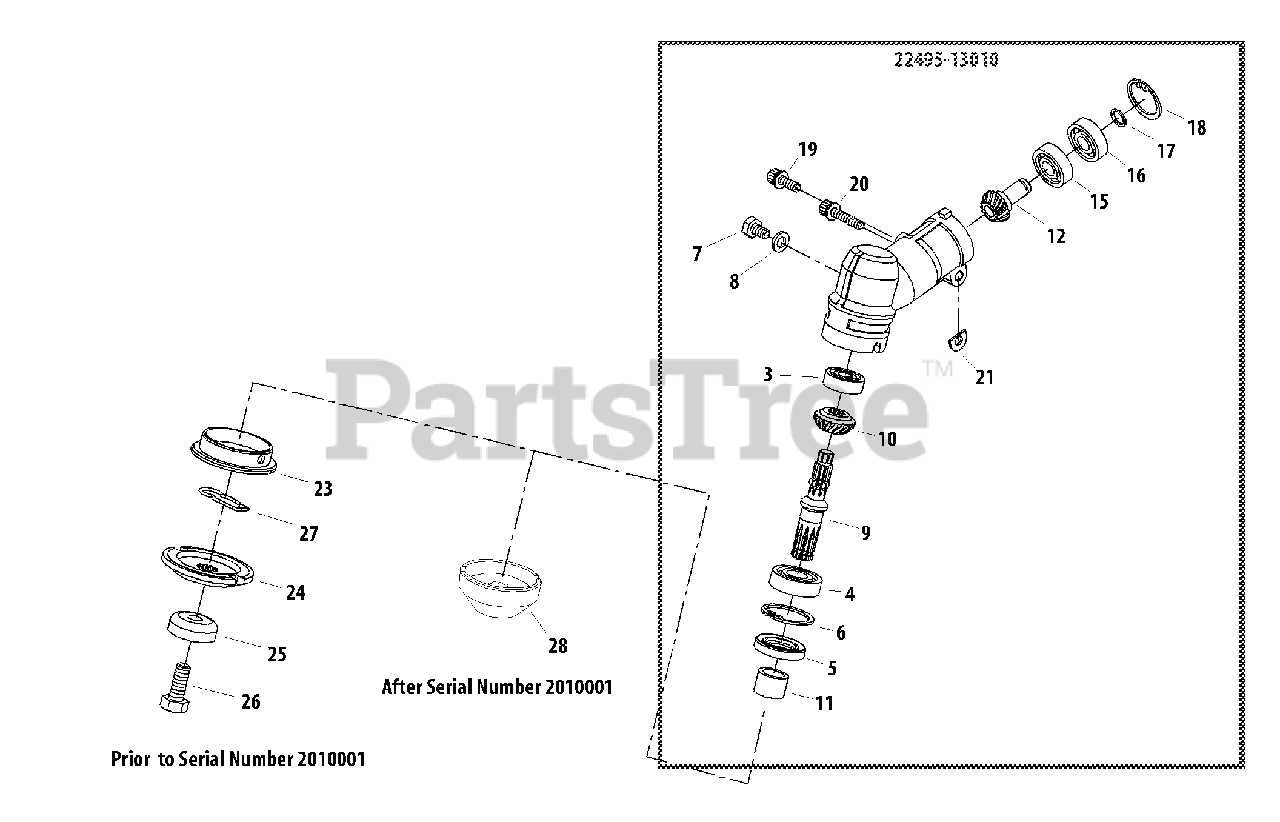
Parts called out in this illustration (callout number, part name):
3	BEARING, BALL - 608DDU
4	BEARING, BALL - 6001
5	SEAL, OIL
6	RING, RETAINING - 28
7	BOLT - 6X10
8	WASHER - 6
9	GEAR - SHAFT
10	GEAR - BEVEL
11	COLLAR
12	GEAR SHAFT ASSY
15	BEARING, BALL - 609
16	BEARING, BALL - 609ZZ
17	RING, RETAINING
18	RING, RETAINING - 24
19	SCREW - 5X16
20	SCREW - 5X25
21	SHIM
23	HOLDER - A
24	HOLDER (B)
25	GUARD
26	BOLT - 8 -- LEFT HAND
27	CLIP
28	HOLDER
22495-13010	GEAR CASE ASSY
